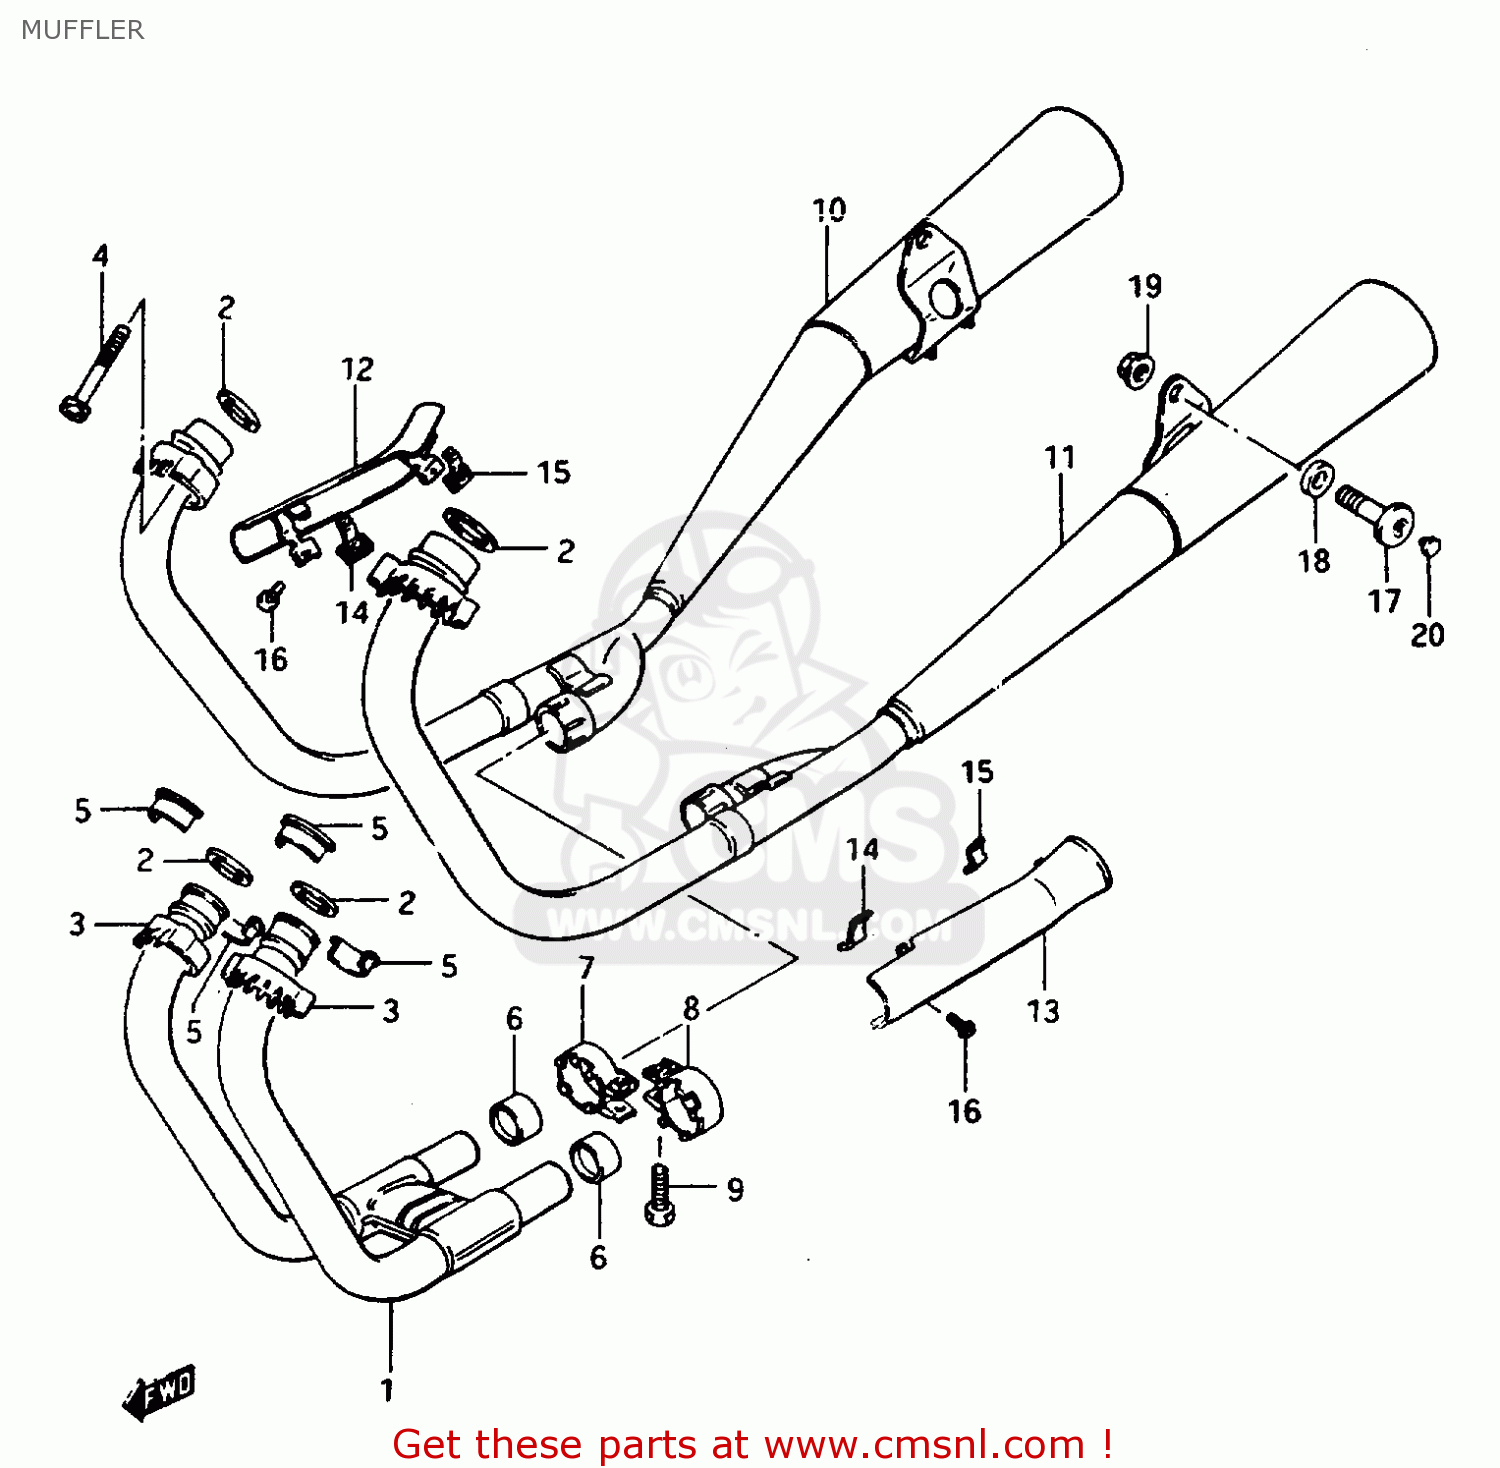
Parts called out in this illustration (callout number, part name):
1	PIPE,EXHAUST,CENTER
2	GASKET,EXHAUST PIPE (NAS)
3	CLAMP(H:21)
4	BOLT
5	PLATE,EXHAUST P
6	CONNECTOR,MUFFLER
7	CLAMP,MUFFLER CONNECTOR
8	CLAMP,MUFFLER CONNECTOR
9	BOLT
10	MUFFLER, RH
11	MUFFLER, LH
12	COVER,MUFFLER,RIGHT
13	COVER,MUFFLER,LEFT
14	CLAMP,MUFFLER COVER
15	CLAMP,MUFFLER COVER
16	SCREW
17	BOLT
18	WASHER(10.5X20X3.2)
19	NUT
20	CAP
